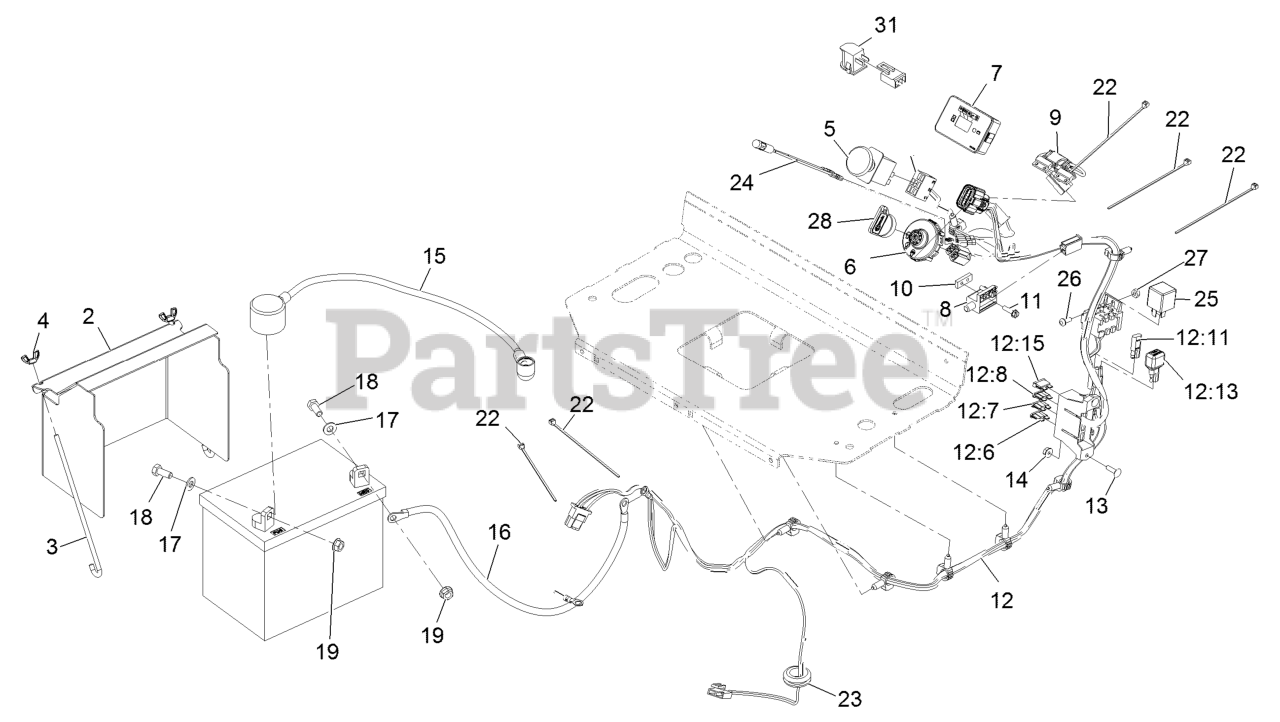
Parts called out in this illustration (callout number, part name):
2	COVER-BATTERY
3	BOLT-HOLDDOWN
4	WINGNUT
5	SWITCH-PTO, ON-ON
7	MODULE-HOUR METER
8	SWITCH-CLOSED, NORMALLY
9	HARNESS-SWITCH, REED
10	PLATE-TAPPED
11	SCREW-HWH
12	HARNESS, WIRE
12:6	FUSE-BLADE, 30 AMP
12:7	FUSE-BLADE, 25 AMP
12:8	FUSE-BLADE, 10 AMP
12:15	FUSE-BLADE, 15 AMP
13	SCREW-CARR
15	CABLE-BATTERY, POSITIVE
16	CABLE-BATTERY, BLACK
17	WASHER-PLAIN
18	SCREW-HH
19	NUT-HHF, SMOOTH
22	TIE-CABLE
23	GROMMET
24	INDICATOR-LED, RED
26	SCREW-PPH
27	NUT-LOCK, NI
28	KEY-IGNITION
31	SWITCH-BAIL
